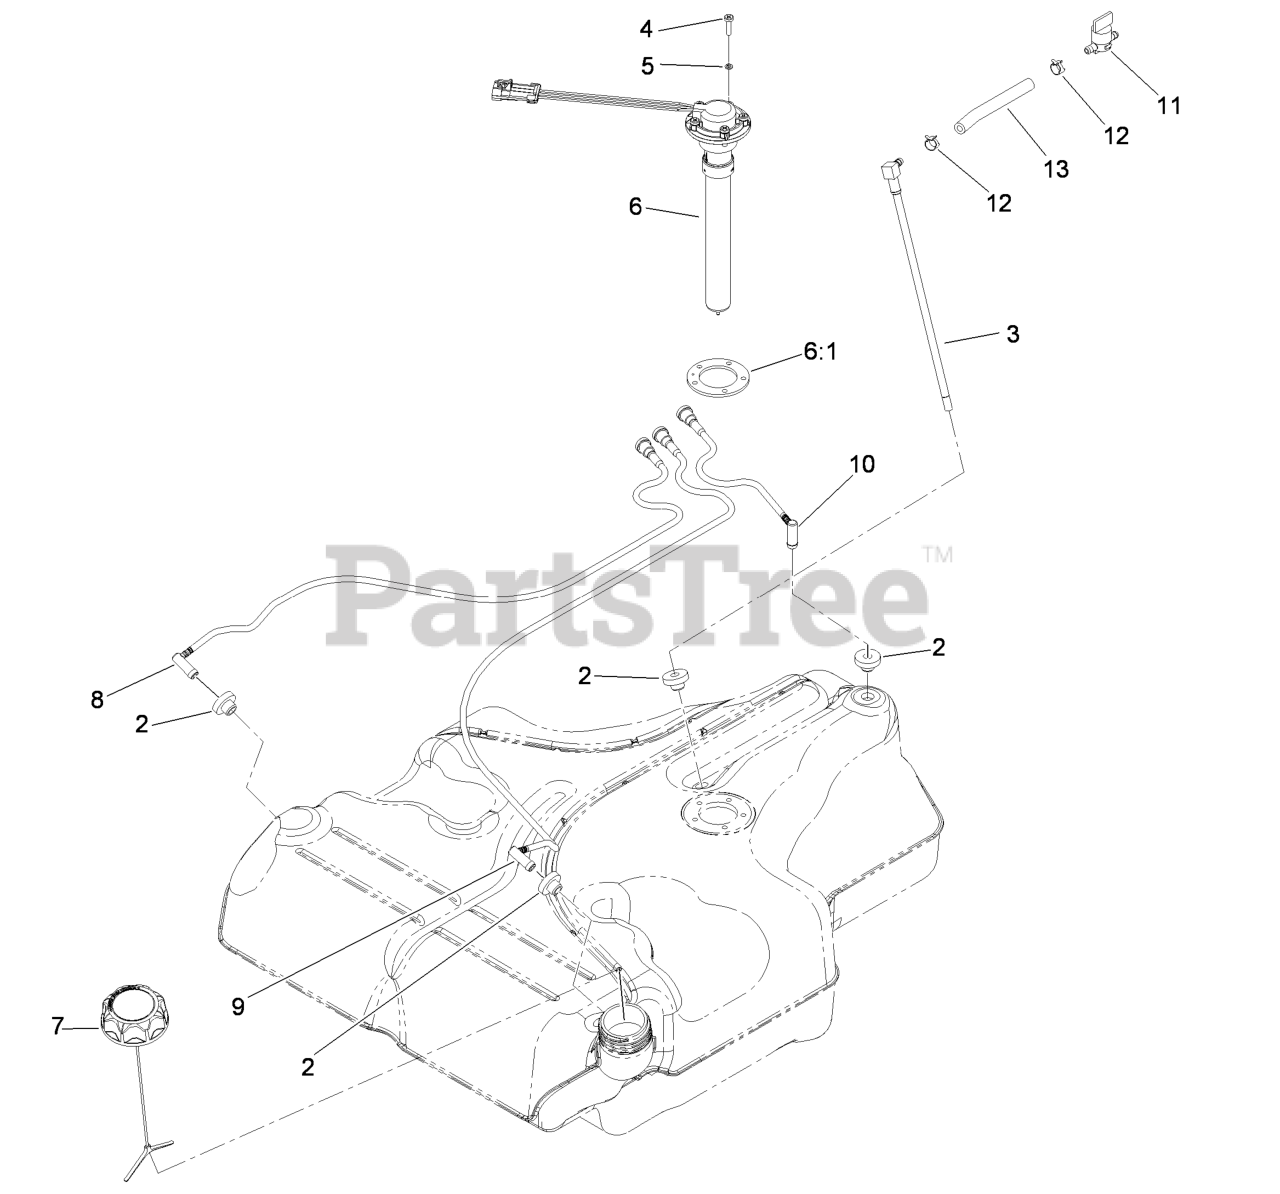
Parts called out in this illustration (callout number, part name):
2	BUSHING
3	FUEL LINE KIT (WITH GROMMET)
4	SCREW-PAN
5	WASHER-LOCK
6:1	GASKET-SENDER, FUEL
8	RH VENT LINE KIT (WITH GROMMET)
9	LH VENT LINE KIT (WITH GROMMET)
10	REAR VENT LINE KIT (WITH GROMMET)
11	VALVE-FUEL
12	CLAMP-HOSE
13	HOSE-FUEL
